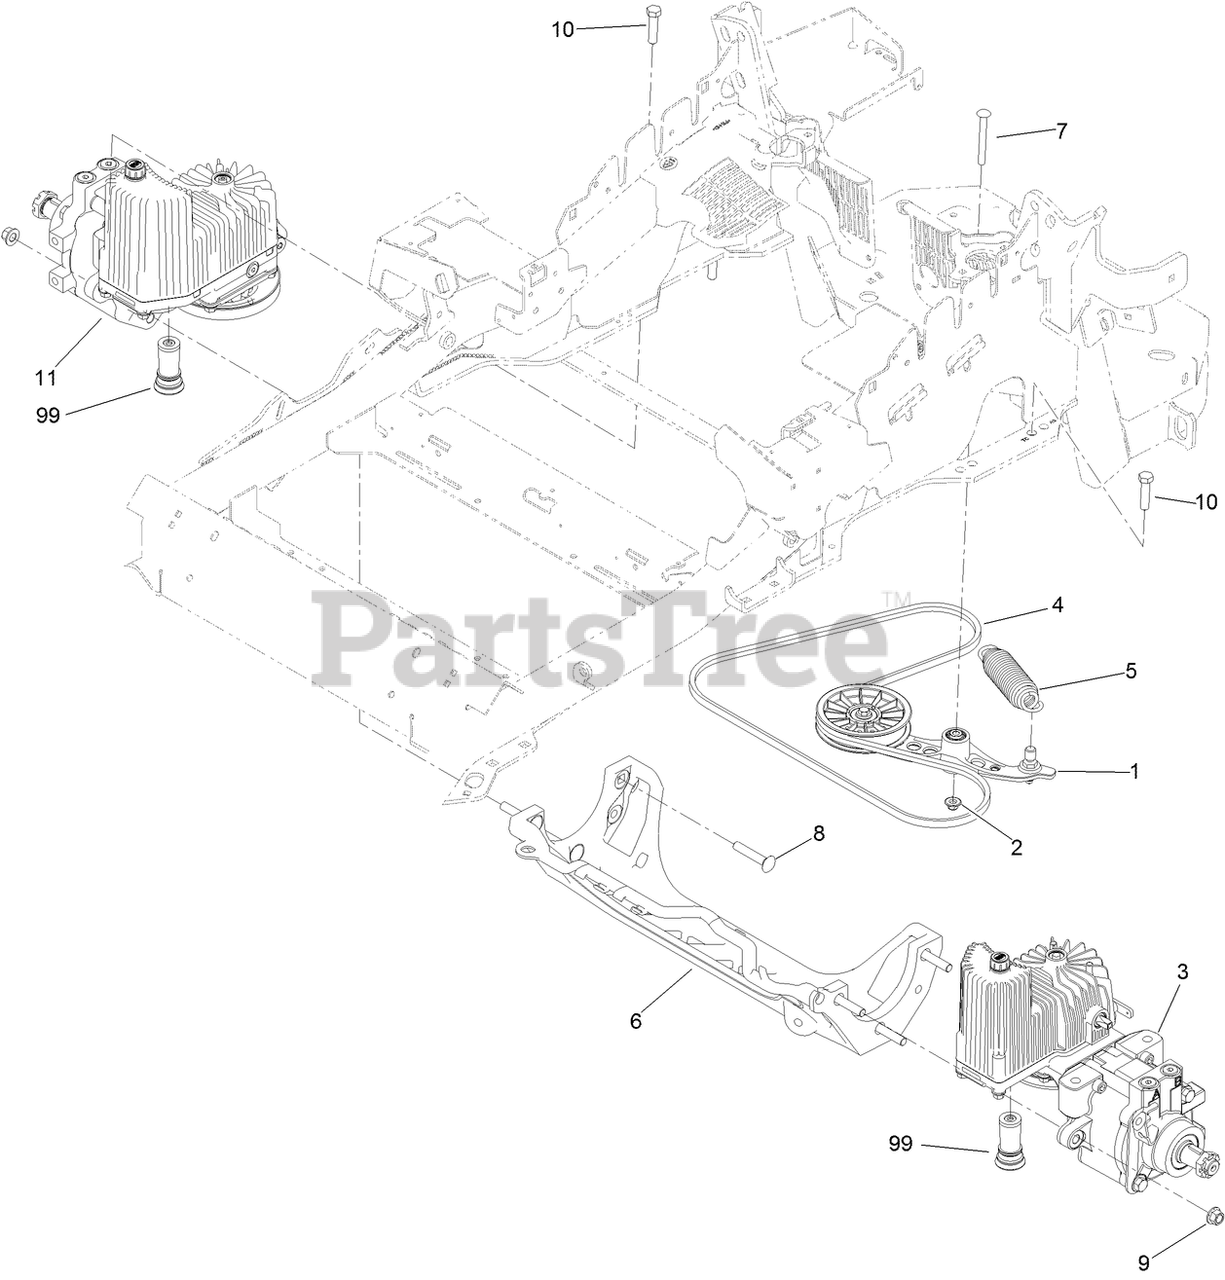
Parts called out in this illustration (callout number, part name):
1	PUMP IDLER ASM
2	NUT-FLANGE, NI
3	LH HYDRO ASM (12CC NO FAN)
4	BELT-V
5	SPRING-EXTENSION
6	CRADLE-HYDRO
7	BOLT-SHOULDER, CARRIAGE
8	SCREW-CARR
9	NUT-LOCK
10	SCREW-HH
11	RH HYDRO ASM (12CC NO FAN)
99	FILTER-HYDRO
